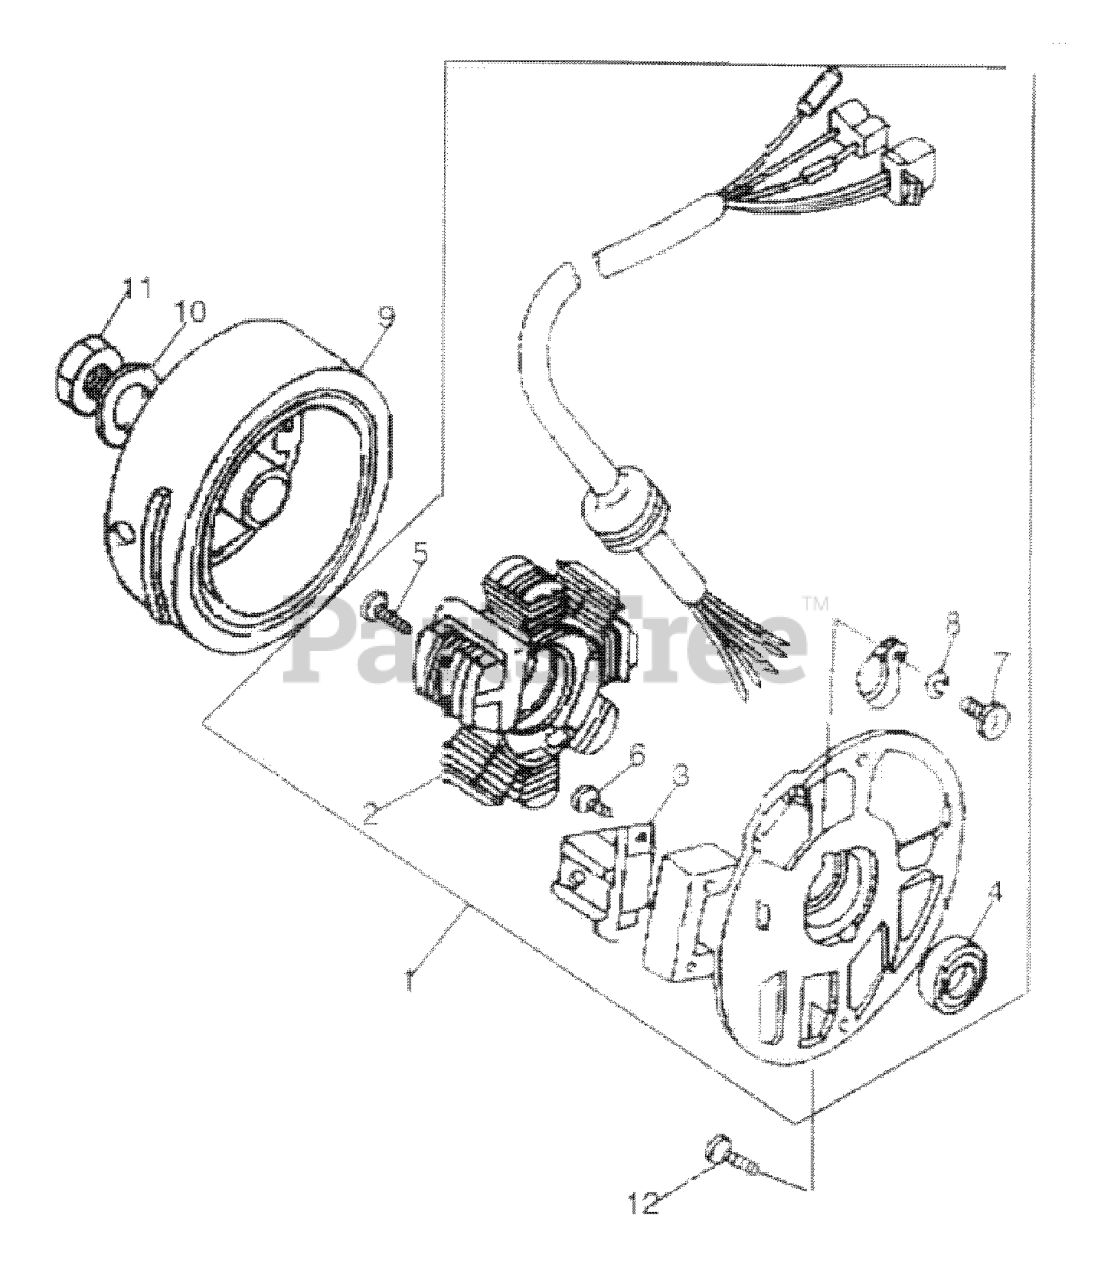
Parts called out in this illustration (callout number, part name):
1	STATOR ASSY
2	COIL GROUP
3	PULSE TRIGGER
4	OIL SEAT
5	SCREW
6	SCREW
7	SCREW
8	WASHER
9	ROTOR ASSY
